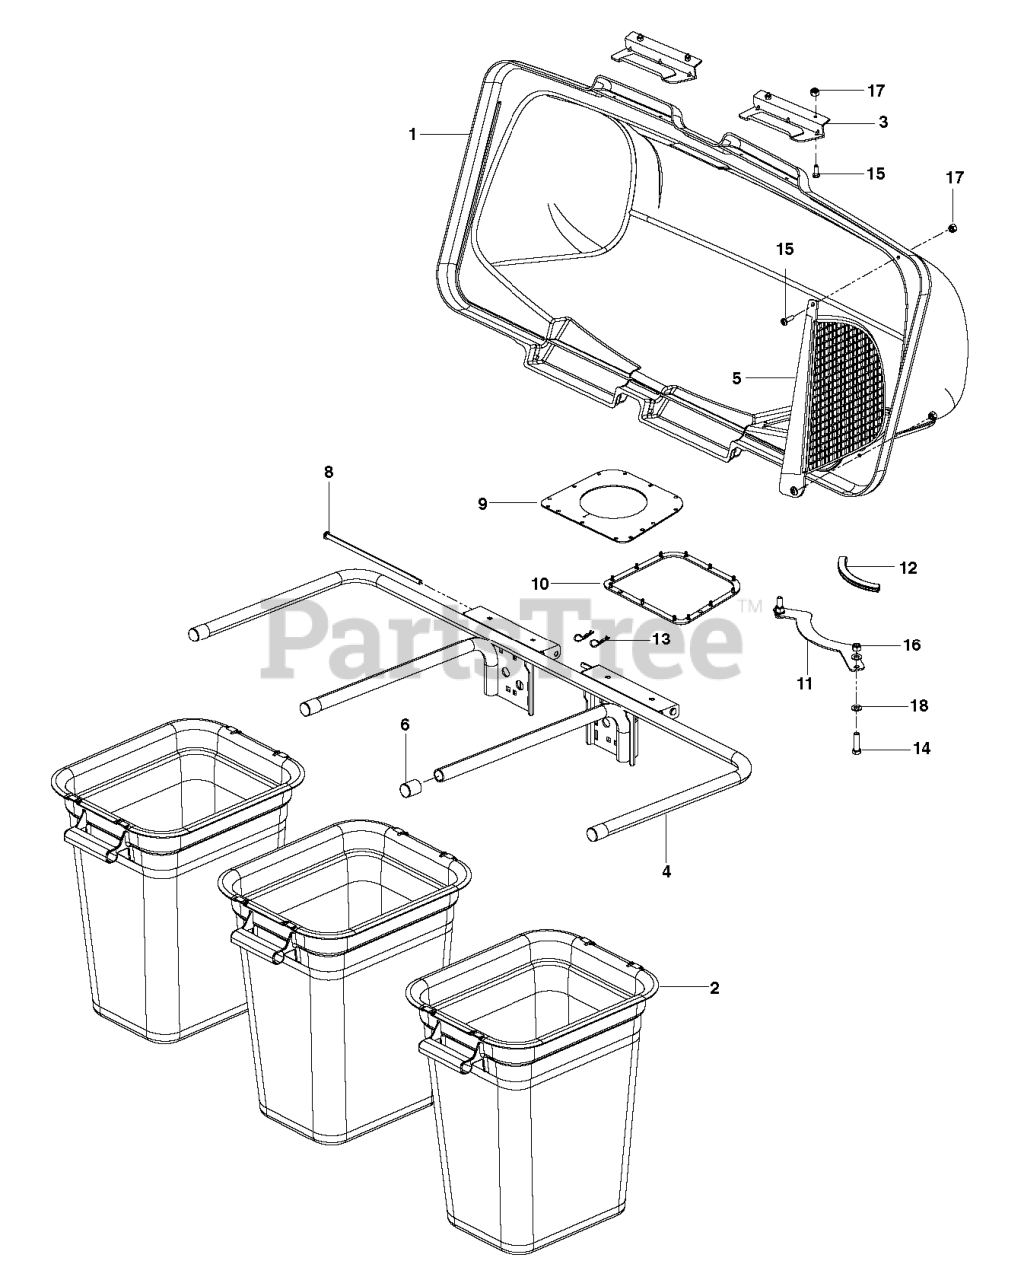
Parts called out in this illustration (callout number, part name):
1	COVER.ASM.3BIN.GENERIC.
2	CONTAINER BAG, SOFT
3	LATCH CER38
4	BAGGER.ASM.FRAME.3BIN.BLACK
5	SCREEN.COVER.BAGGER
6	PLUG, TUBING END
8	BAGGER.HINGE.PIN
9	SEAL.BAGGER.TOP.3-BIN.BLK
10	GASKET.COVER.BAGGER
11	SUPPORT.CHUTE.COLLECTION.BLACK
12	RP.FLEX TRIM, BLK-LENGTH 1 FT
13	RETAINER SPRING
14	HCS 5/16C X 1 1/4
15	SCREW #10-24 X 5/8
16	5/16-18 NYLOC FLANGE NUT
17	NUT 10-24 NYLOC
18	FLAT WASHER 5/16 SAE
